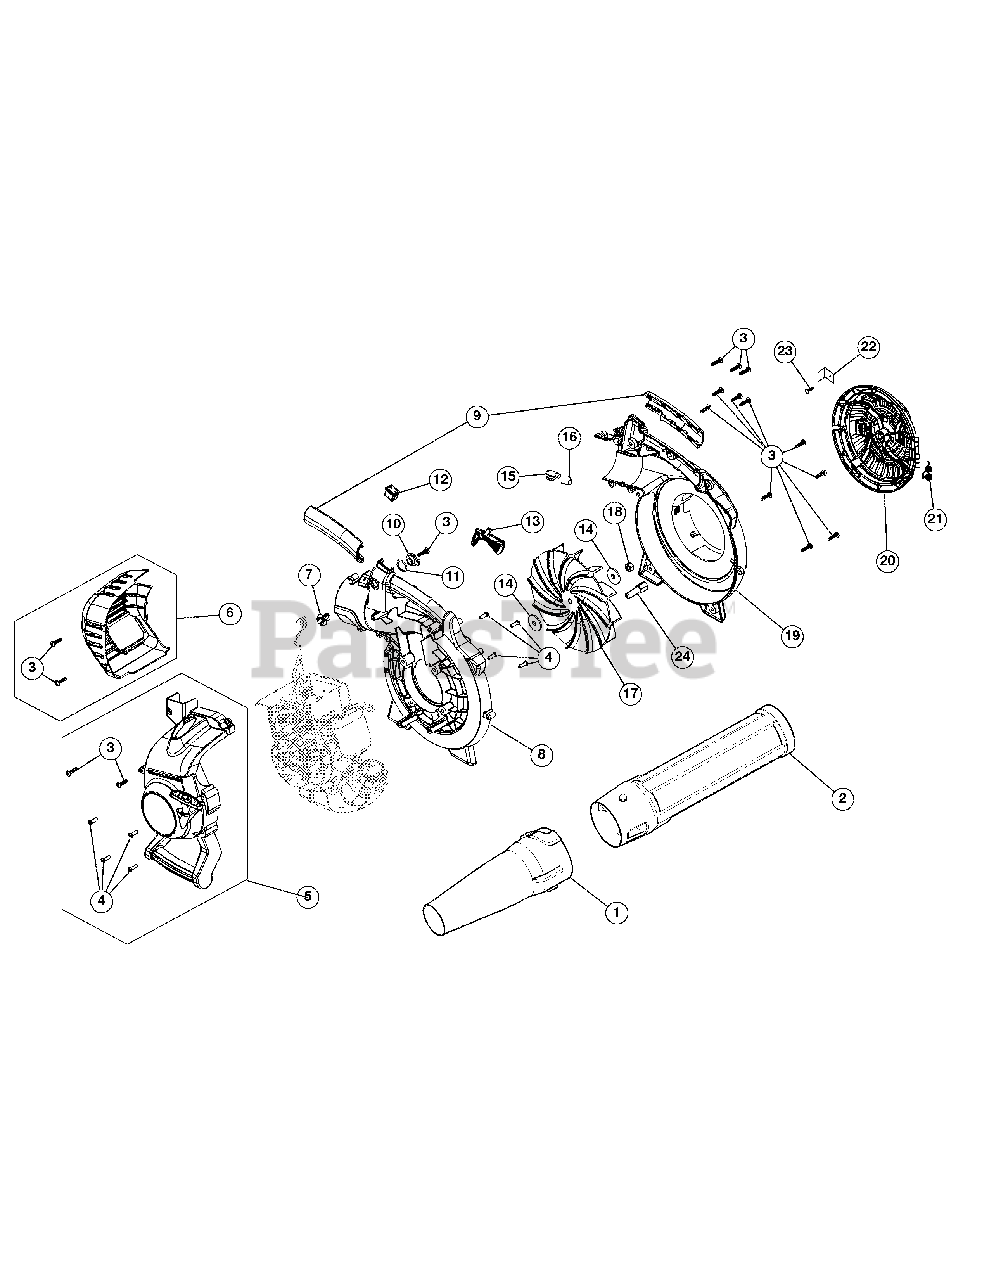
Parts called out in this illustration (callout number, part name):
1	Nozzle
2	Upper Blower Tube
4	Screw
5	Engine Cover Assembly (Incl. 3 & 4)
6	Muffler Cover Assembly (Incl. 3)
7	Outer Trigger Lock
8	Impeller Housing
9	Handle Grips
10	Inner Trigger Lock
11	Wavey Washer
13	Throttle Trigger
14	Washer
15	Latch Tube
16	Latch Spring
17	Impeller
18	Nut
19	Impeller Housing
20	Intake Cover
21	Spring
22	Door Lock
23	Screw
24	Adapter
